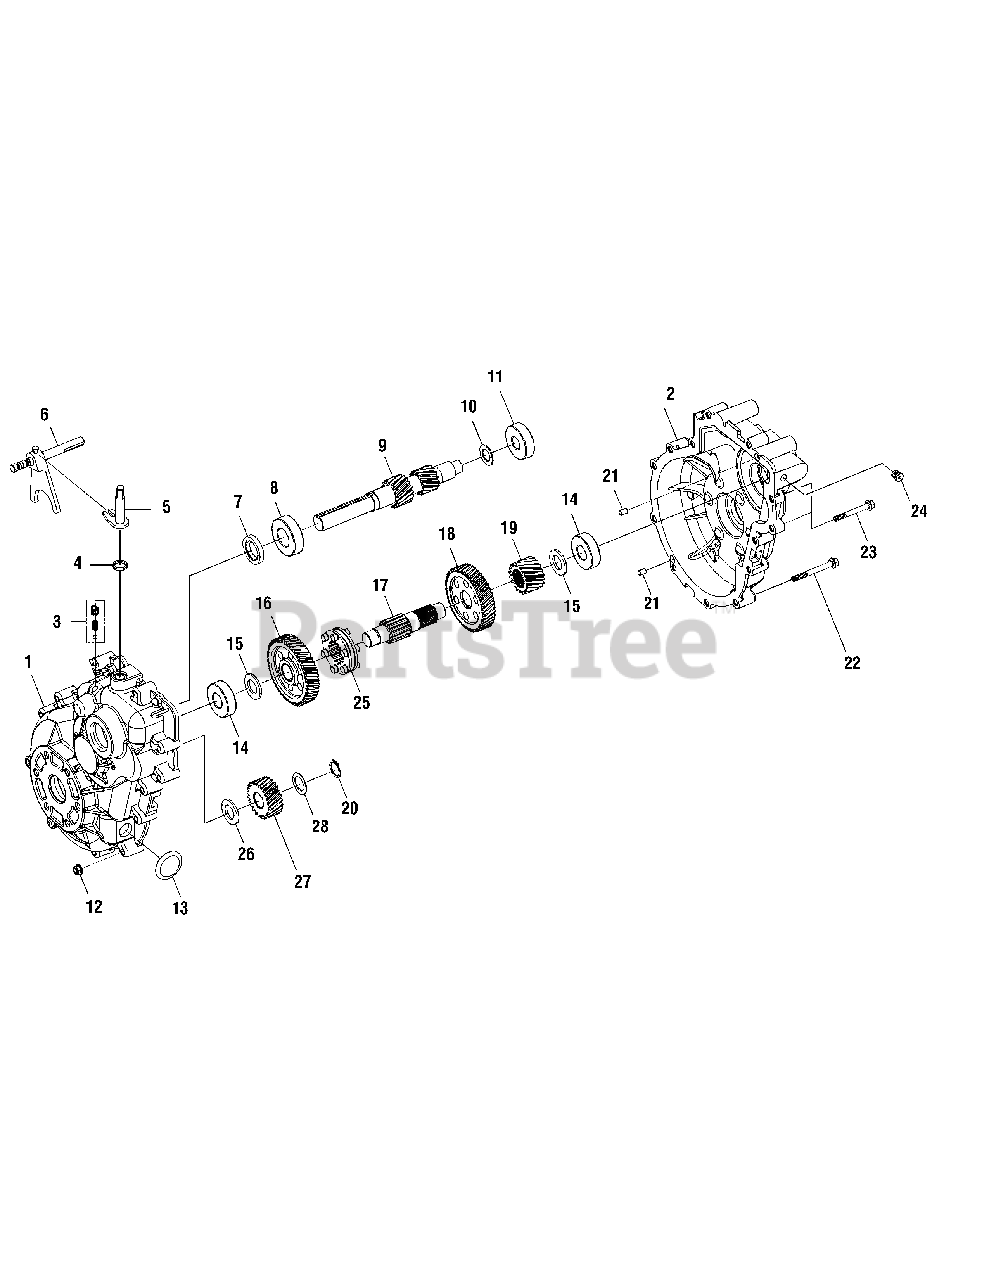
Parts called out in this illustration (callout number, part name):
1	Housing, Axle, w/Idler Shaft
2	Housing, Axle, Finished
3	Kit, Detent
5	Assembly, Actuator
6	Assembly, Shift Rod
8	Bearing, Ball
9	Shaft, Input
10	Kit, Shim
11	Bearing, Ball
13	Plug, Rubber
14	Bearing, Ball
15	Spacer, Flat
16	Gear Assembly, Forward
17	Shaft, Intermediate
18	Gear Assembly, Reverse
19	Gear, Helical (Pinion)
20	Ring Retaining
22	Screw, Flange Head
23	Screw, Flange Head
25	Gear, Clutch
26	Washer, Thrust
27	Gear, Assembly, Idler
28	Washer, Thrust
